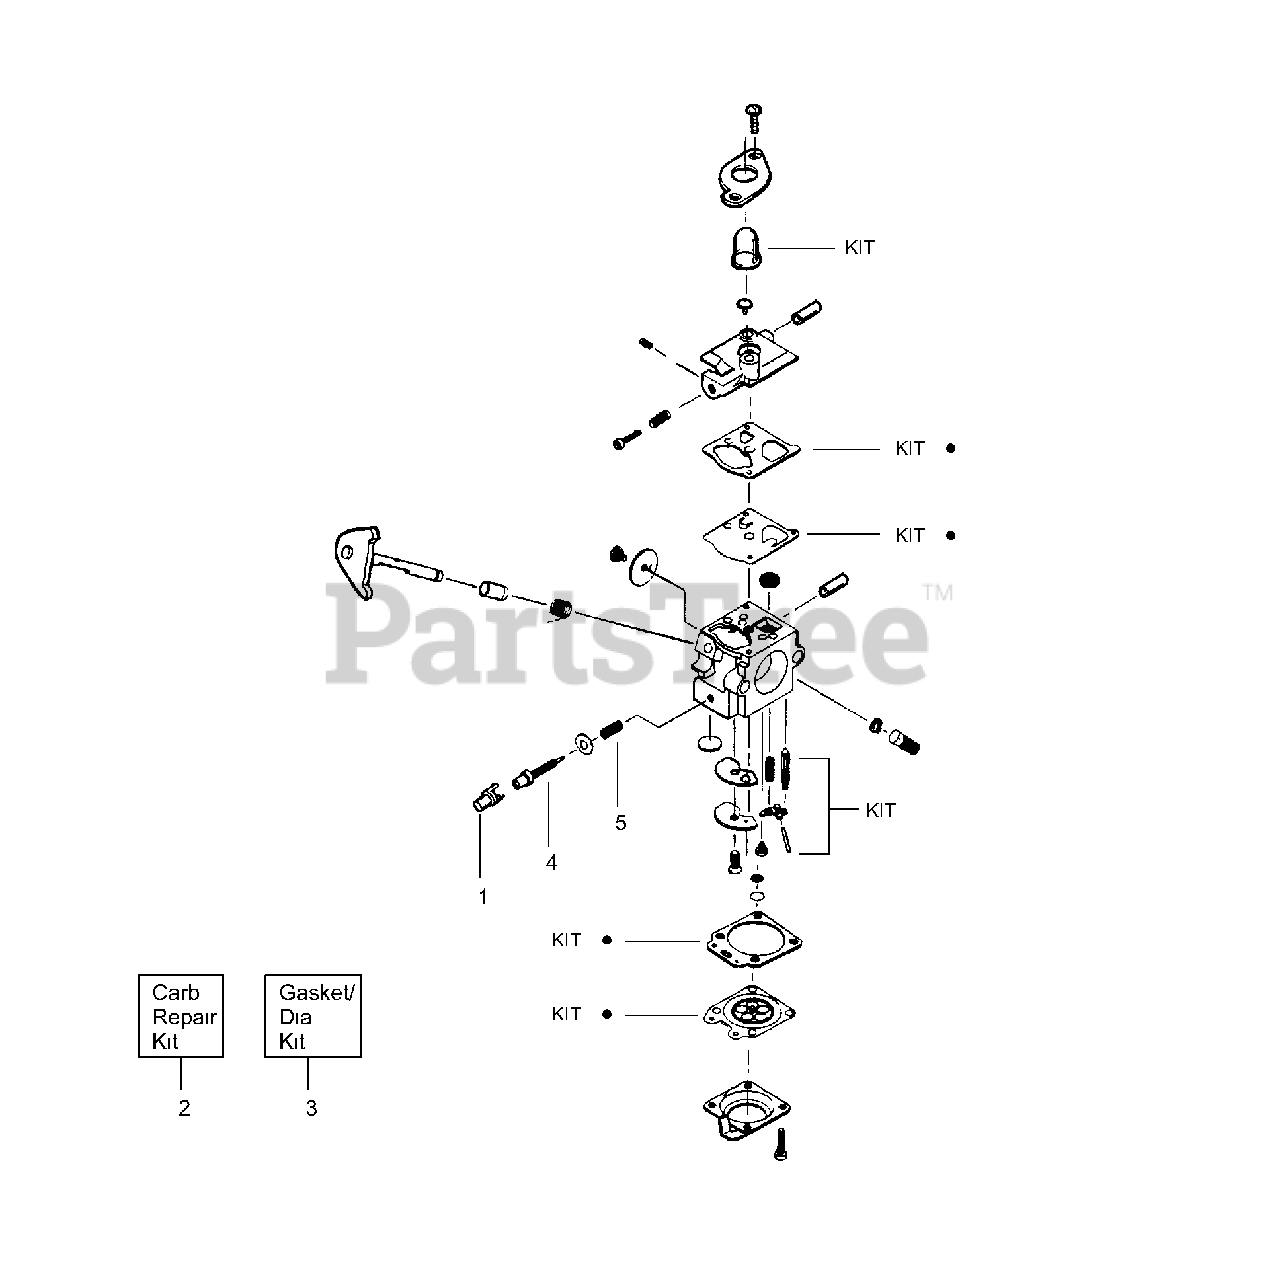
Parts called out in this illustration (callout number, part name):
1	Limiter Cap
2	Carburetor Repair Kit
3	Gasket Diaphragm Kit
4	Needle--Idle
5	Spring--Idle Needle
